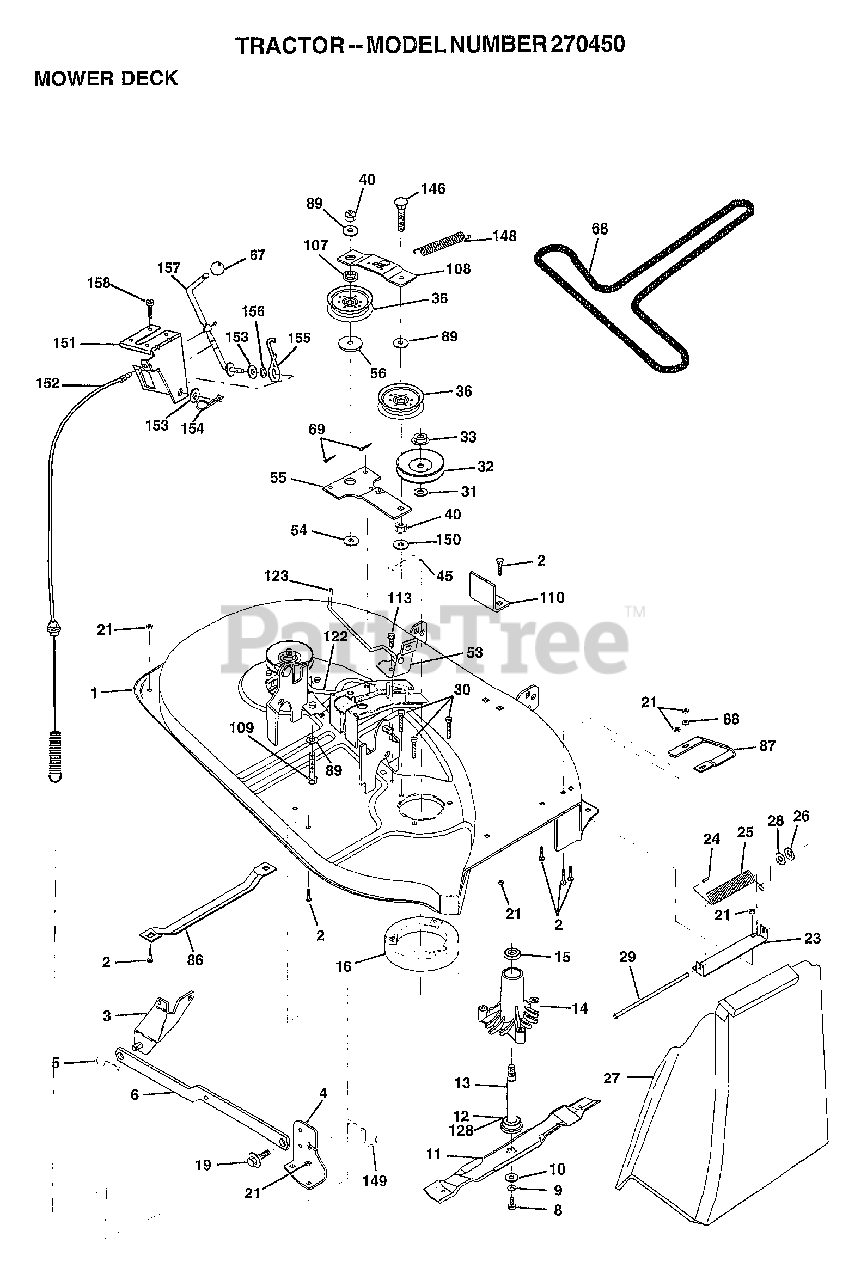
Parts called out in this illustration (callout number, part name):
1	MOWER HSG ASSY
2	BOLT
3	BRKT ASM SWAY BAR
4	BRKT SWAY BAR DECK
8	BLADE BOLT
10	WASHER.HARD.BLADE
11	"BLADE.38""V.MULCH"
12	BEARING.BALL
14	HSG ASM MANDREL
15	BEARING
16	STRIPPER RND MWR
19	BOLT SHD 5/16-18
21	NUT
23	BRKT DEFLECTOR
24	CAP-SLEEVE LT
25	SPRING TORSION
26	NUT PUSH M
27	DEFLECTOR, SHIELD
28	WASHER
29	ROD-HINGE T
30	"SCREW-THD ROLL,WA"
31	WASHER
32	PULLEY.MANDREL.38
36	FLAT IDLER PULLEY
45	RETAINER M
53	BRAKE ASM
54	HARDENED WASHER
55	IDLER ARM ASSY
56	SPACER.RETAINER.MOWER
67	KNOB.OVAL.CUSTOM
68	BELT.V.T-PATH
86	RUNNER-LH M
87	RUNNER RH
88	WASHER M
89	WASHER GT
107	RETAINER SPACER
108	IDLER ARM STIFF
109	BOLT
110	UPSTOP DECK FT 38
113	SCREW
122	BRAKE ROD LH
123	ROD
128	WASHER.FELT.
146	BOLT
148	SPRING RETURN IDLER
149	RETAINER SPRING
150	WASHER PM
151	BRKT CLUTCH CABLE
152	CLUTCH CABLE
153	WASHER FLAT
154	SPRING RETAINER
155	SPRING RETENTION LVR CLUTCH CAB
156	SPACER
157	ROD.CLUTCH.CABLE.3/8
158	SCREW LT
